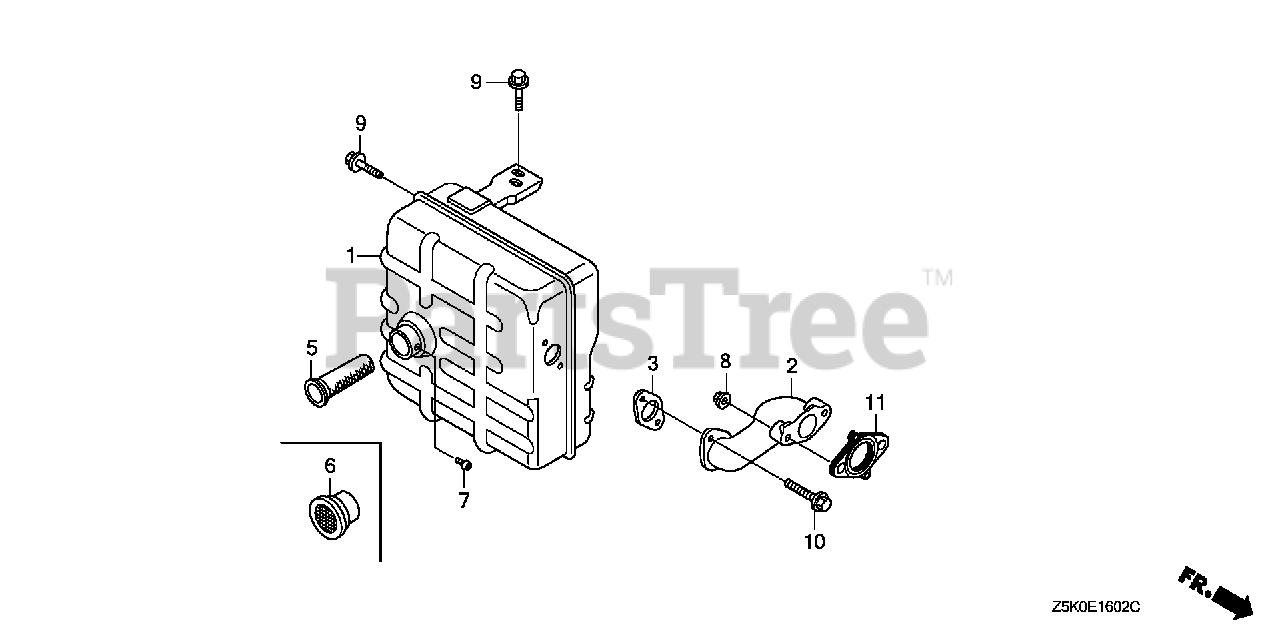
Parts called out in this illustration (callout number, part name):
1	MUFFLER (SDMO)
3	GASKET, EX. PIPE
5	ARRESTER, SPARK
7	SCREW, TAPPING (4X8)
8	NUT, FLANGE (8MM)
9	BOLT, FLANGE (8X16)
10	BOLT, FLANGE (8X20)
11	GASKET, EX. PIPE
